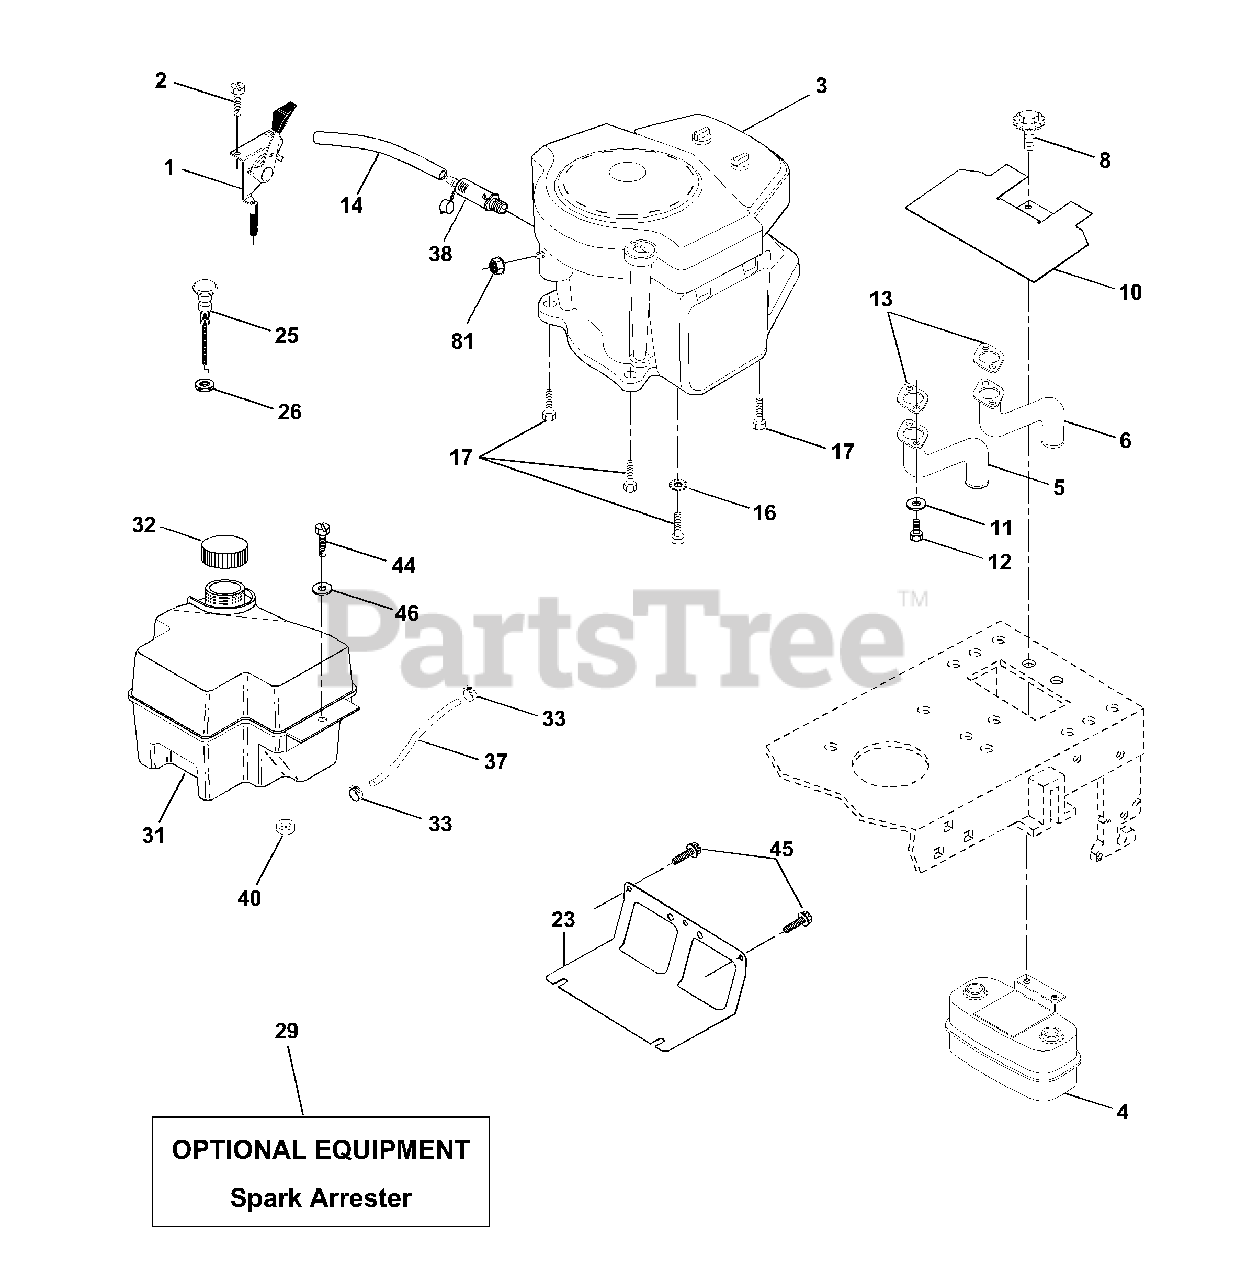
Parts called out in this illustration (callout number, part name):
1	Control Throt
2	Screw Hex Thd Cut 1/4-20x5/8 T
4	Muffler Exhaust
5	Exhaust Asm. Lh
6	Exhaust Asm. Rh
8	Bolt 5/16-18unc x 3/4 w/sems
10	Heat Shield Lt
11	Washer Lock Hvy. Helical 1/4
12	Screw Hex Hd Cap 5/16-18 x 3/4
13	Gasket Muffler
14	Tube Drain Oil Easy
16	Washer Lock Ext Tooth 3/8
17	Screw Thdrol 3/8-16x1-1/2 Tytt
23	Shield BRN/DBR Guard
25	Control Choke
26	Nut Keps 3/8-24 UNF
29	Arrestor Spark
31	Tank Fuel
32	Cap Fuel
33	Clamp Hose Blk
37	Line Fuel
38	Plug Drain Oil Easy
40	Bushing Snap Nyl Black
44	Screw Hexwsh Thdrol 1/4-20 x 3/4
45	Screw Hex wsh Thdrol 3/8-16 x 3/4
46	Washer 9/32 x 7/8 x 16 Ga.
81	Nut Keps Hex 1/4-20 unc
